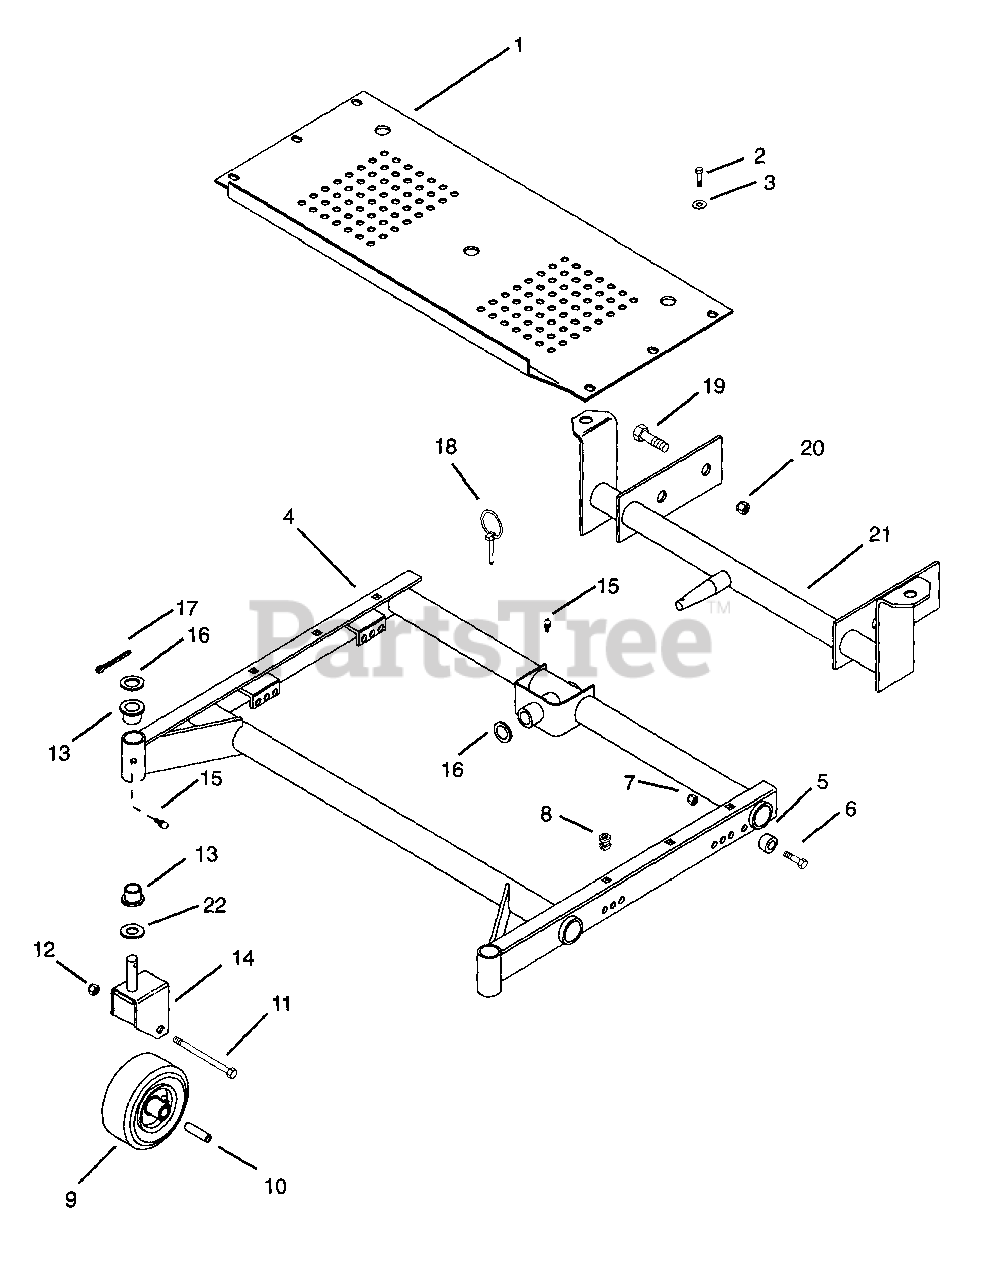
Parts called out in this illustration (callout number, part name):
1	Footboard
2	Screw-Machine .25-20
3	Washer-Flat-Steel .281 x .625 x .065
4	Weldment Mower Frame
5	Bushing .391 x .626 x .670
6	Bolt-Hex .38-16 x 1.50 Grade 5
7	Nut-Locking-Nylon .375-16 Grade 2
8	Clip, U-Type
9	Wheel, Gauge 11 x 4-4
10	Bushing, Caster Fork
11	Bolt-Hex .50-13 x 6.50
12	Nut-Locking-Nylon .50-13 Grade 5
13	Bushing-Flange 1.020 x 1.385 x .75 x 1.75
14	Weldment, Castor Fork
15	Fitting-Lube .25-28 x .256
16	Washer-Hardened-Thrust 1.002 x 1.552 x .030
17	Pin-Cotter .188 x 1.50
18	Pin-Klik .25 x 1.75
19	Bolt-Hex .62-11 x 1.50
20	Nut, Locking 5/8-11
21	Weldment, Mower Frame Mounting
22	Washer-Flat-Steel 1.007 x 1.542 x .062
